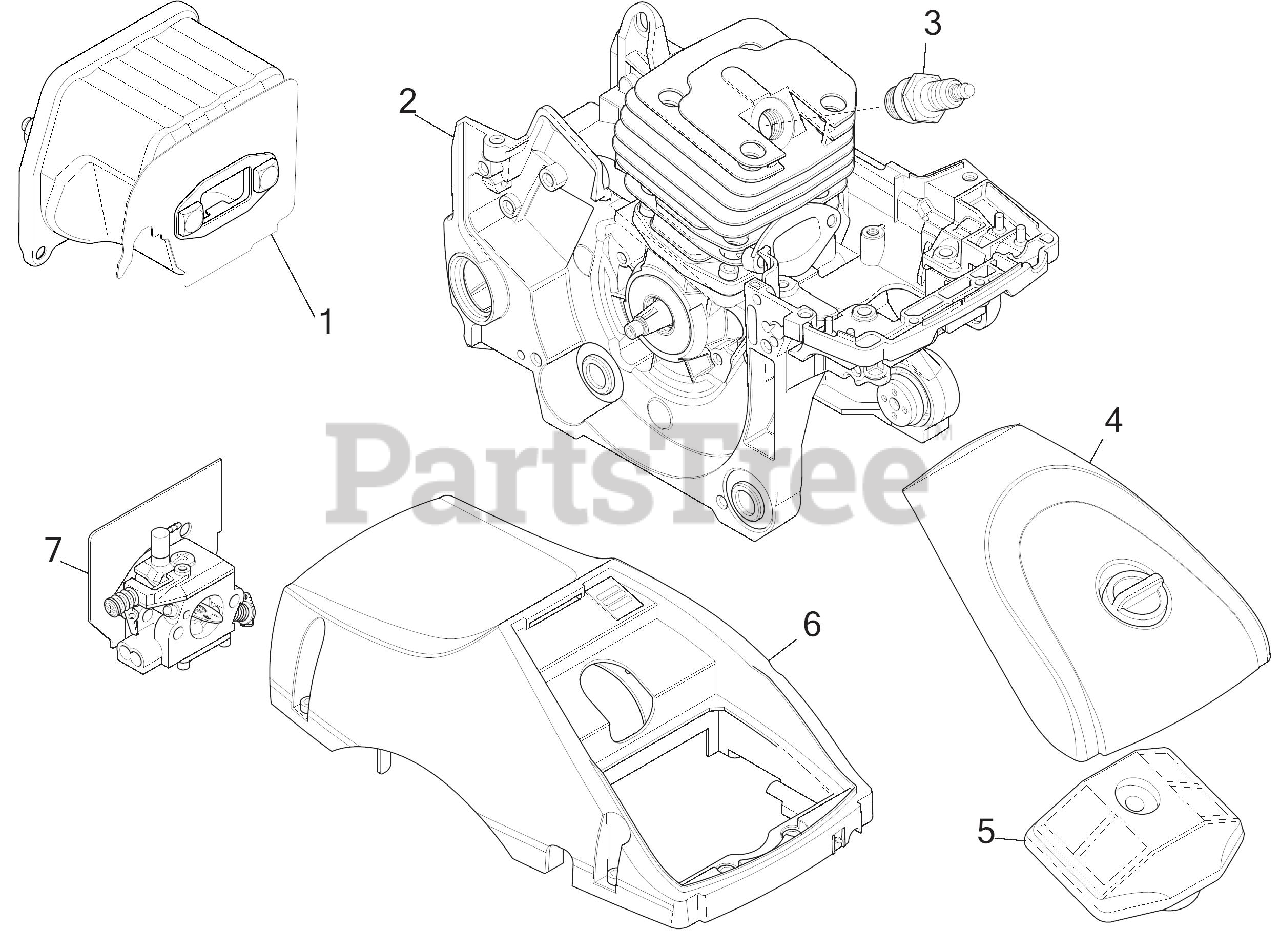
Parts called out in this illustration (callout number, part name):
1	MUFFLER ASSEMBLY
2	SHORT BLOCK 46CC YD4600.8-31000
3	SPARK PLUG:L8RTF
4	COVER ASSEMBLY:AIR FLTR
5	AIR FILTER W/SEAL
6	COVER:CYL:CHAINSAW
7	CARBURATOR:CHAINSA
